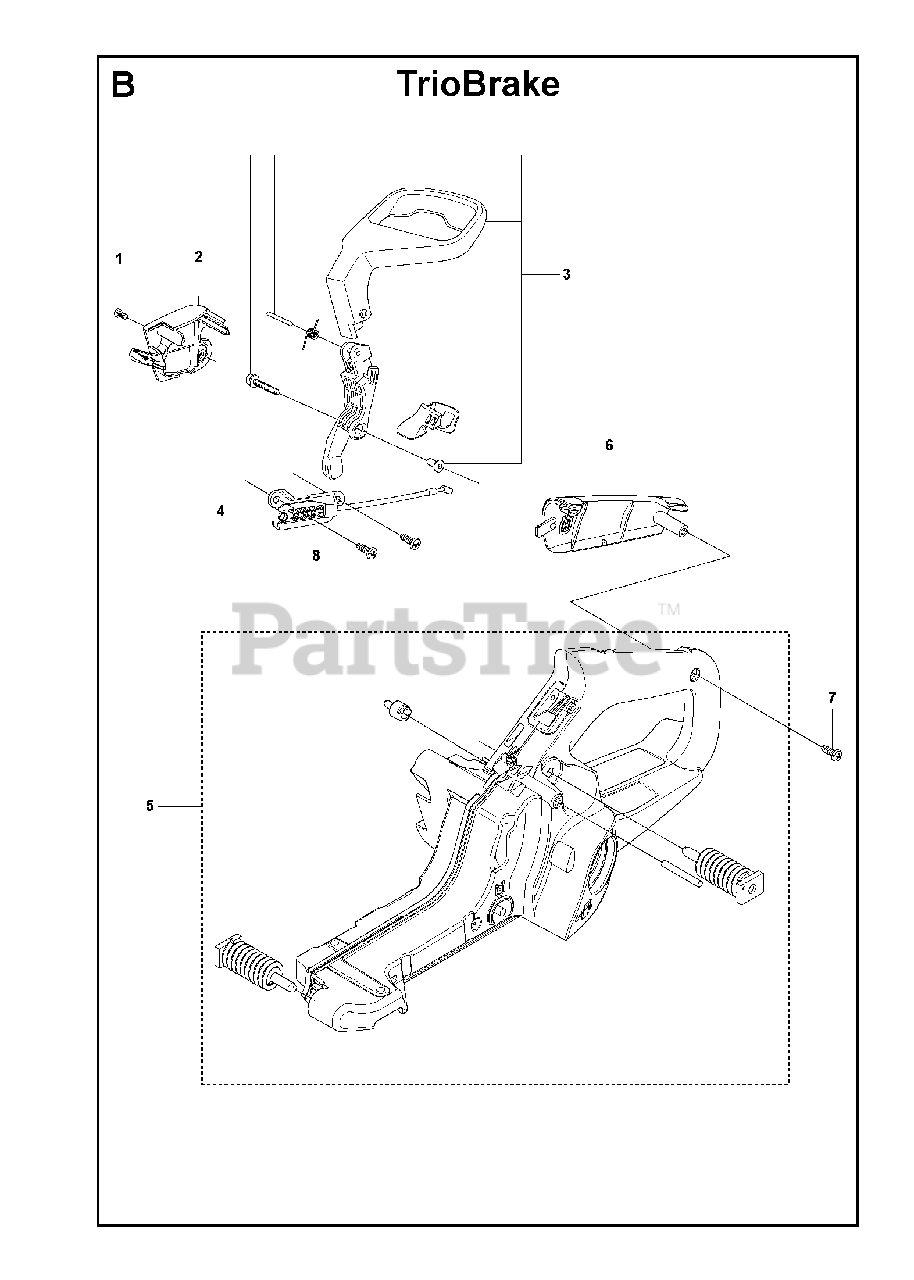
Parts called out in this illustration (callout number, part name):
3	Hand Guard
5	Fuel Tank Assembly
6	HANDLE INSERT
